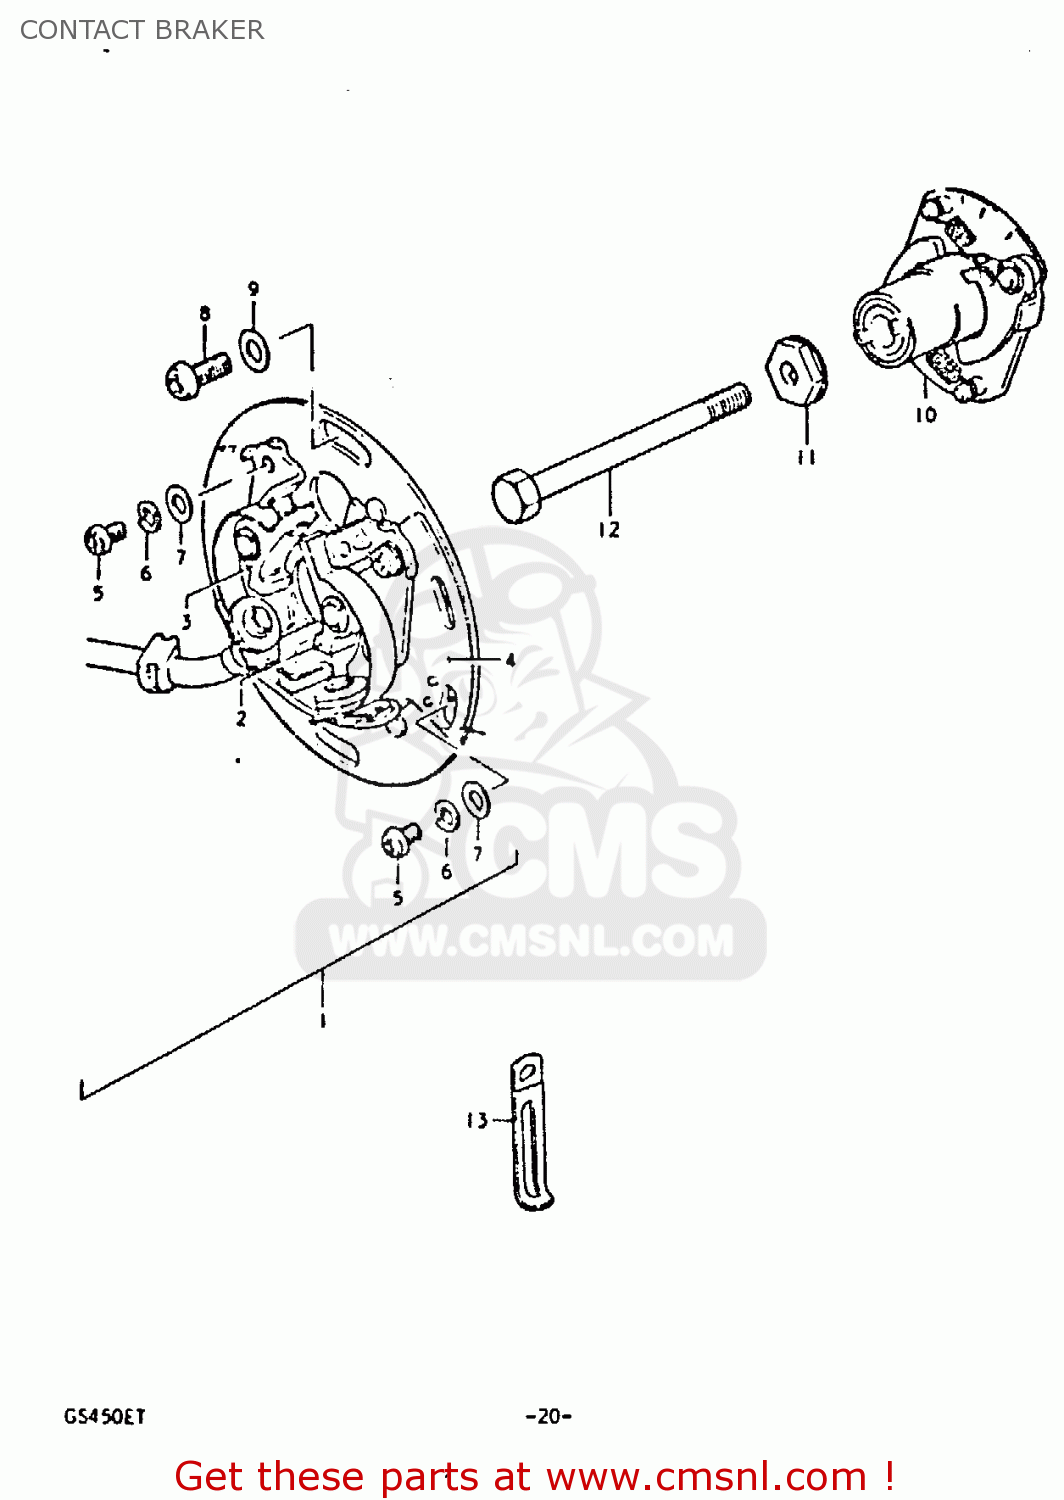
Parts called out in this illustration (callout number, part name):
1	BREAKER ASSY, CONTACT
2	POINT ASSY,CONTACT,R
3	POINT ASSY,CONTACT,L
4	PLATE,CONTACT POINT
5	SCREW 4X6
6	LOCK WASHER
7	WASHER
8	SCREW(5X12)
9	WASHER
10	GOVERNOR ASSY, ADVANCE
11	WASHER,CONTACT BREAKER
12	BOLT 6X60
13	CLAMP L:35
